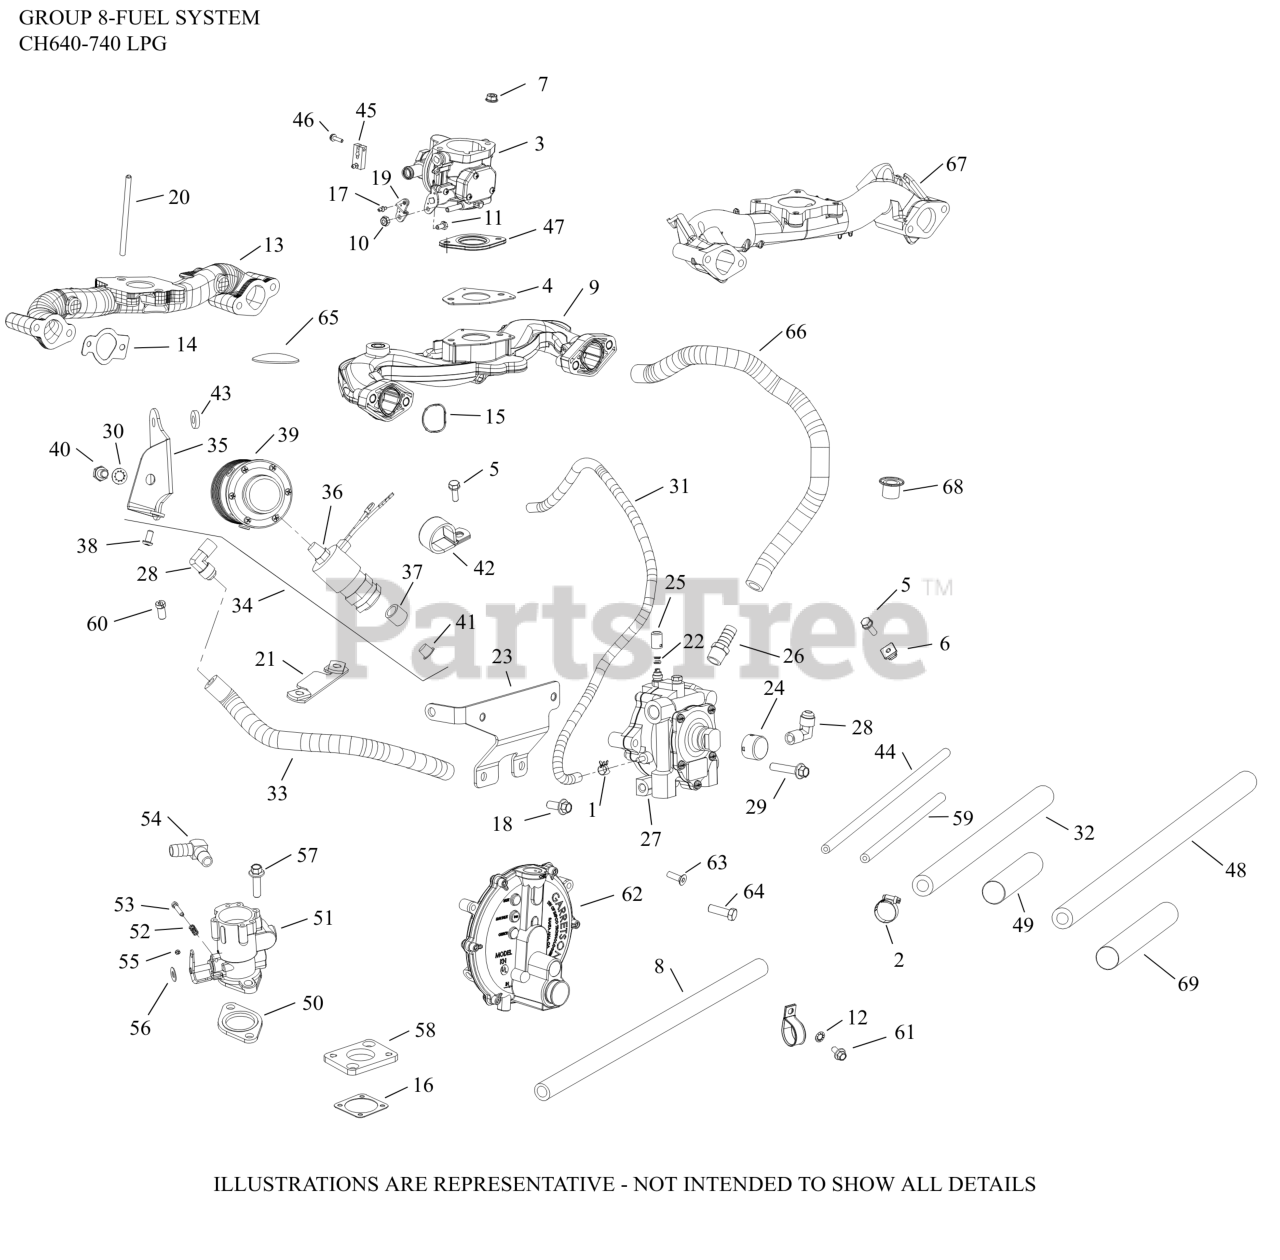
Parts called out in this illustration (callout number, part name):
3	KIT, CARBURETOR W/GASKETS
7	NUT, FLG M6X1.0
14	GASKET, INTAKE MANIFOLD-USE 24 041 79-S
28	FITTING, LPNG FUEL
47	GASKET, CARBURETOR
48	LINE, LP FUEL (29")
49	SLEEVE, ANTI- ABRASION-USE 25 431 19-S
62	REGULATOR ASSY(GASEOUS FUEL)
